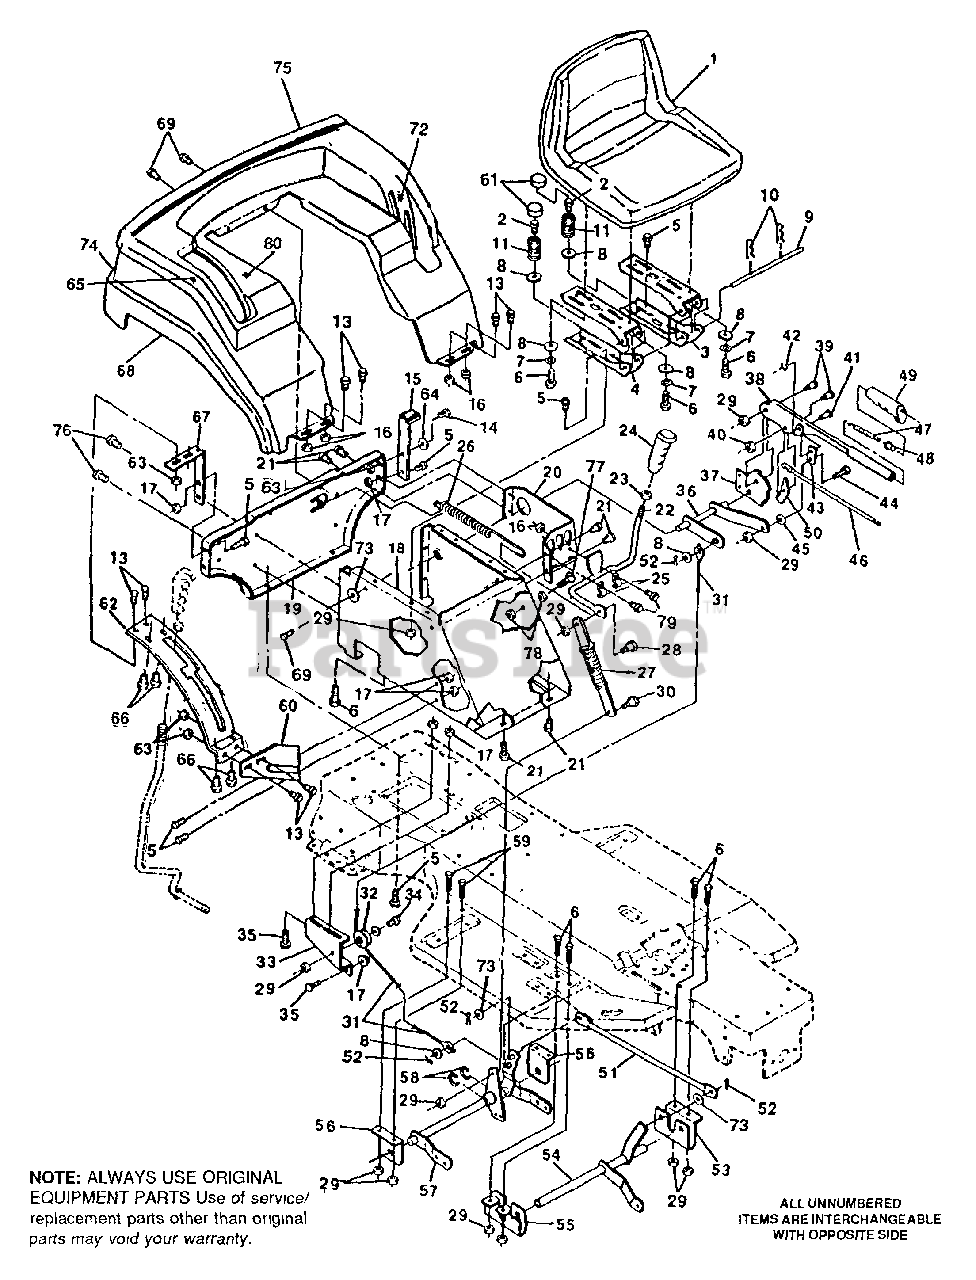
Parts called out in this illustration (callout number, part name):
2	Screw, 5/16-18 x 5/8 In.
3	Channel, Seat L. H.
4	Channel, Seat R. H.
5	Screw, Hx Hd, Wd Fl 5/16-18 x 3/4 In.
6	Screw, Hx Hd, 5/16-18 x 3/4 In.
7	Washer, Lock 5/16 In.
8	Washer, Flat, 11/32 In.
9	Rod, Seat Support
10	Hair Pin, .073 Dia. x 1 13 In.
11	Seat Spring
12	Washer, Flat, 9/32 In.
13	Screw, Hx Hd, 1/4-20 x 5/8 In
14	Screw, 1/4-20 x 3/4 In
15	Fender Support, L H
16	Nut, Lock 1/4-20 Thd
17	Nut, Hx, Wd Fl, Lk 5/16-18 Thd
18	Seat Support
19	Support, Fender & Seat
20	Bracket, Support Engage
21	Screw, Hx Wshr Hd Tap, 5/16-18 x 1/2 In
22	Assembly, Engagement Rod
23	Nut, Hx Ctrlk, 1/2-13 Thd.
24	Handle, Lift
26	Spring, Tension
27	Assembly, Spring Cartridge
28	Shoulder Bolt, 7/16 In
29	Nut, Hx Ctrlk, 5/16-18 Thd
30	Shoulder Bolt, 5/16-18 Thd
31	Cable, Deck Lift
33	Assembly, Pulley Bracket
34	Shoulder Bolt, 5/16-18 Thd
35	Bolt, Carriage, 5/16-18 x 5/8 In
36	Assembly, Upper Shaft
37	Quadrant
38	Lift Lever
39	Shoulder Bolt, 5/16-18 Thd.
40	Nut, Hx Wd Fl Lk 5/16-18 Thd.
41	Clevis Pin
44	Shoulder Bolt, 5/16-18 Thd
46	Actuator Rod
47	Spring, Height Adjust
48	Knob, Height Adjust
49	Handle, Lift
50	Pawl, Height Adjust
52	Cotter Pin
53	Bracket, L. H Front Hanger
54	Assembly, Front Lift Shaft
55	Bracket, R. H. Front Hanger
56	Bracket, Hanger
57	Assembly, Rear Lift Shaft
59	Screw, Hx Hd, 5/16-18 x 5/8 In
60	Support, Shift Plate
61	Cover, Seat Spring
62	Quadrant
63	Nut, Hx, Wd Fl Lk, 1/4-20 Thd
64	Washer, Flat
65	Decal, Speed Hydro
66	Screw, Hx Hd, Tap #10 x 1/2 In
67	Fender Support, R H.
69	Screw, Hx, Wshr Hd, Tap 1/4-20 x 5/8 In.
70	Decal, Gear Shift, 6 Speed
71	Decal, Gear Shift, Neutral
72	Decal, Mower Deck Clutch ON/OFF /Deck Cutting Height
73	Washer, Flat, 13/32 In
74	Decal, Hydrostatic
75	Decal, Rear Fender
76	Screw, Tap, 5/16-18 x 7/8 In
77	Screw, Hx, 3/8-16 x 2-1/4 In
78	Nut, Hx Keps, 3/8-16 Thd
79	Screw, 1/4-20 x 1/2 In
80	Decal, Husqvarna, USA
